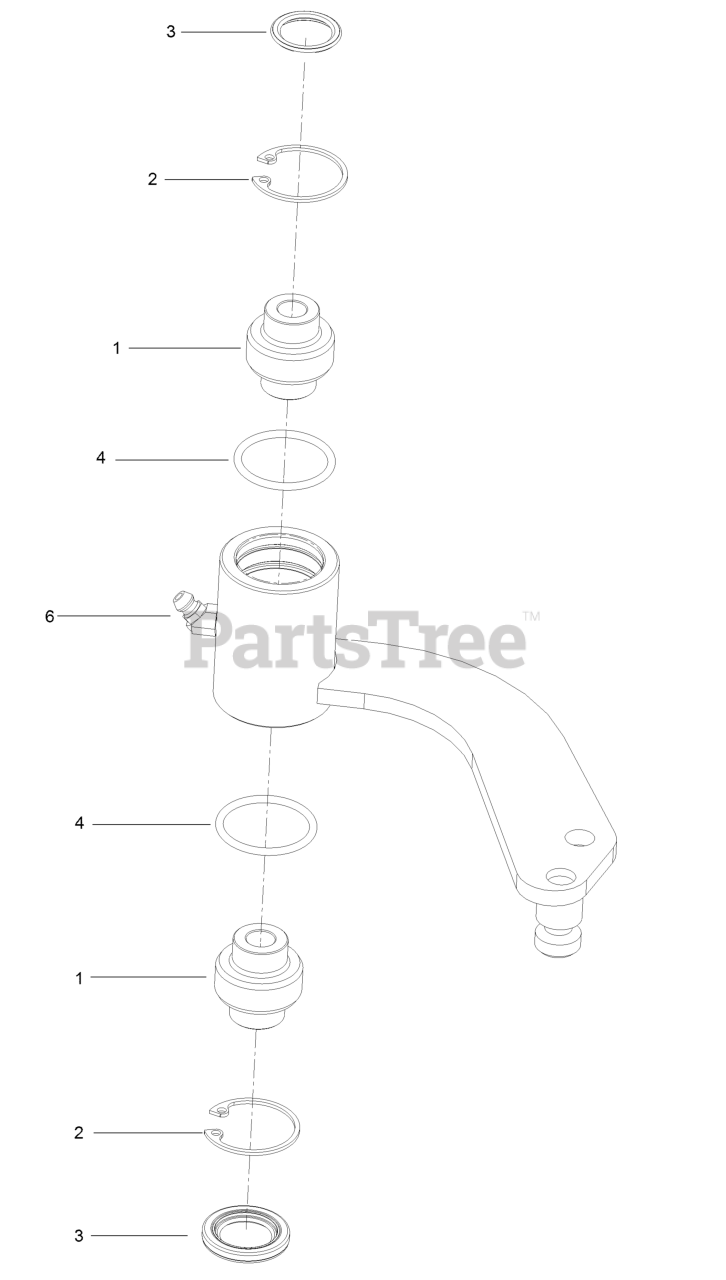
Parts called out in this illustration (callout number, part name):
1	Bearing-Spherical
2	Ring-Snap
3	Seal-Lip, Single
6	Fitting-Lube, 45 DEG
